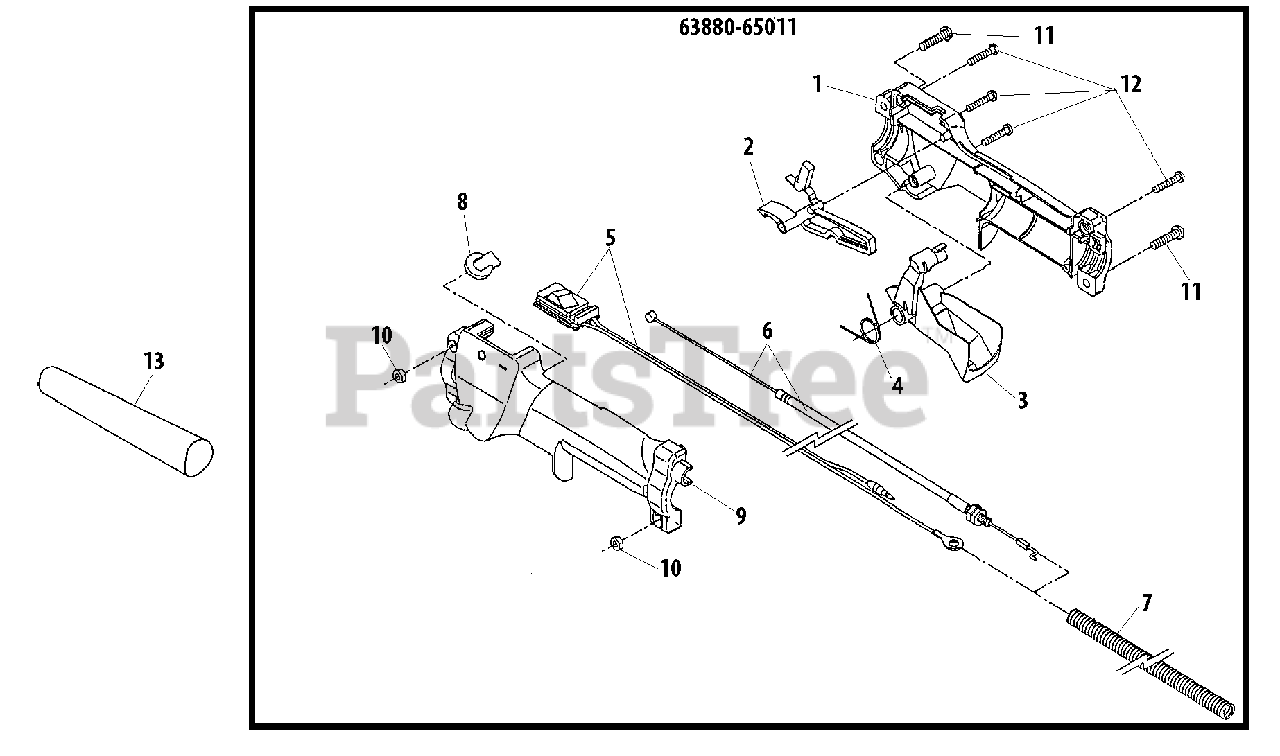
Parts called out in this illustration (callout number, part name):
1	CONTROL HANDLE - RIGHT
2	LEVER, THROTTLE LOCKOUT
3	TRIGGER, THROTTLE
4	SPRING, THROTTLE RETURN
5	SWITCH, ON-OFF
6	CABLE, THROTTLE
7	TUBE, PLASTIC PROTECTIVE
8	PLUG
9	CONTROL HANDLE - LEFT
10	NUT M5
11	SCREW M5×20
12	SCREW, TAPPING M4×20
